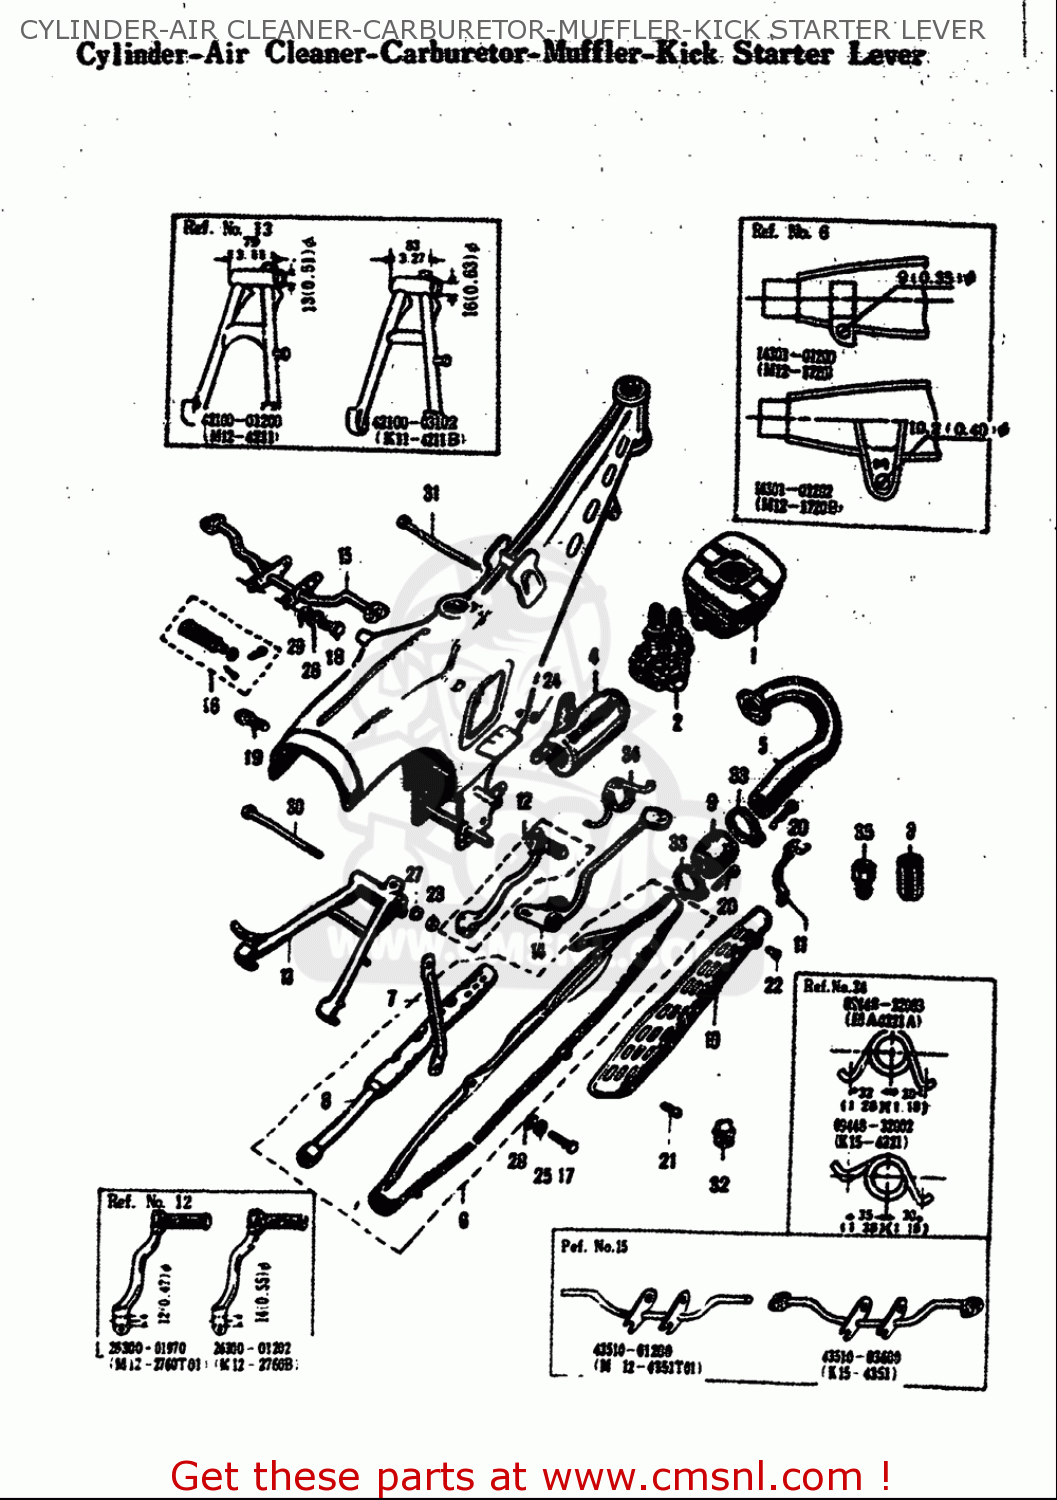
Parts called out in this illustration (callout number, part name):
18	BOLT
19	BOLT
23	NUT
24	NUT
25	WASHER,LOCK
26	WASHER,LOCK
27	WASHER,LOCK
28	WASHER
29	WASHER
30	BOLT
32	PLUG SET
